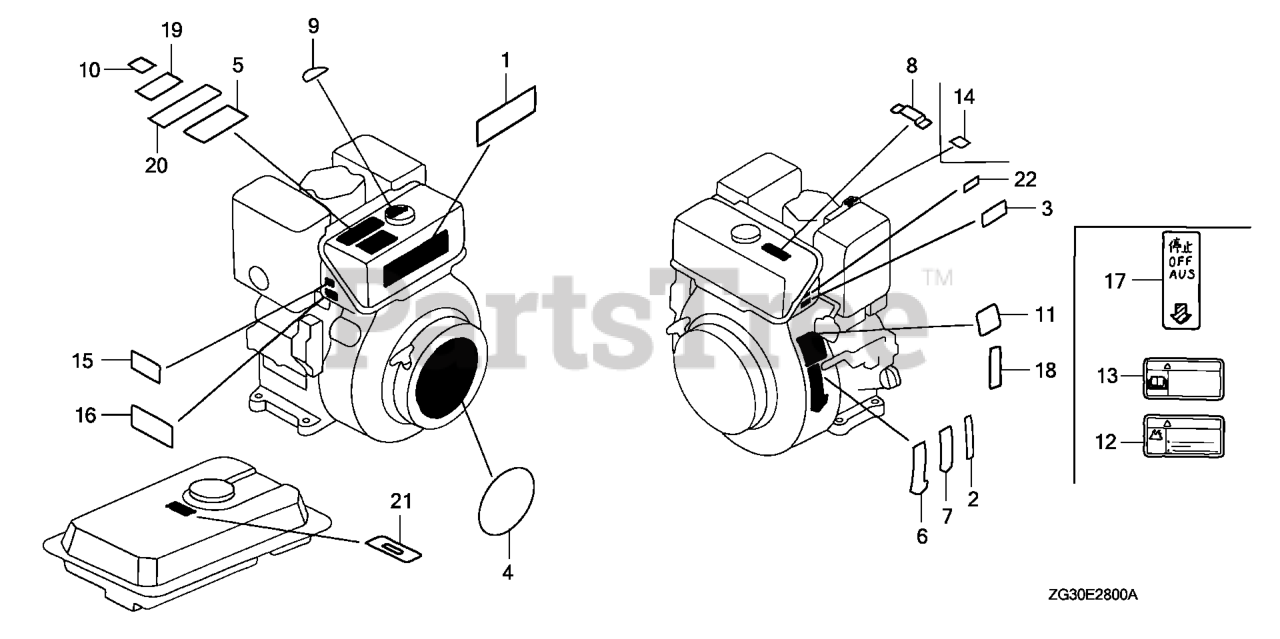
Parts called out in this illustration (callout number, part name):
1	EMBLEM (GD410)
5	LABEL, CAUTION(ENGLISH) (FRENCH)(GERMAN)(SPANISH)
6	MARK, THROTTLE (E)
8	MARK, FUEL (EXTERNAL)
9	MARK, USE FUEL (E)
11	MARK, OIL CAUTION (E)
